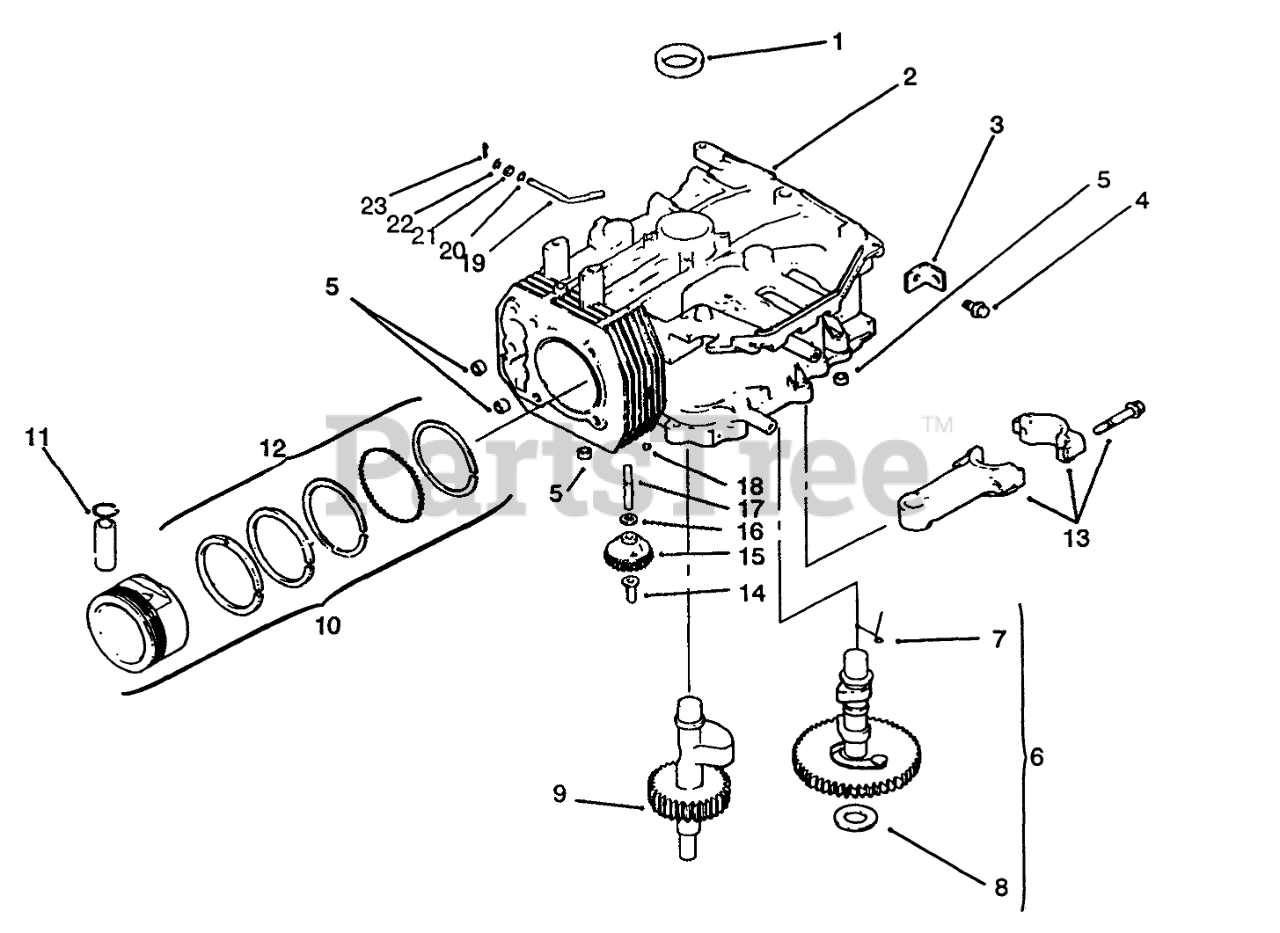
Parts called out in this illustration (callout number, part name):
1	Seal-Crankshaft (Only On: 72042, 72063, 72062, 72043)
3	Strap-lifting (Only On: 72042, 72063, 72062, 72043)
4	Screw M8x1.25x22 (Only On: 72042, 72063, 72062, 72043)
5	Dowel-Locating (Only On: 72042, 72063, 72062, 72043)
6	Kit-Camshaft INC 7-8 (Only On: 72042, 72063, 72062, 72043)
7	Spring-Actuating (Only On: 72042, 72063, 72062, 72043)
8	Shim-Camshaft A/R (Only On: 72042, 72063, 72062, 72043)
8	Shim-Camshaft A/R (Only On: 72042, 72063, 72062 72043)
9	Shaft-Balance (Only On: 72042, 72063, 72062, 72043)
10	Piston ASM STD INC 11-12 (Only On: 72042, 72063, 72062, 72043)
10	Piston ASM .25 INC 11-12 (Only On: 72042, 72063, 72062, 72043)
10	Piston ASM .50 INC 11-12 (Only On: 72042, 72063, 72062, 72043)
11	Retainer-Piston Pin (Only On: 72043, 72042, 72063, 72062)
12	Ring Set STD (Only On: 72042, 72063, 72062, 72043)
12	Ring Set .25 (Only On: 72043, 72042, 72063, 72062)
12	Ring Set .50 (Only On: 72042, 72063, 72062, 72043)
13	Connecting Rod STD (Only On: 72042, 72063, 72062, 72043)
13	Connecting Rod .25 (Only On: 72042, 72063, 72062, 72043)
14	Pin-Governor Regulating (Only On: 72042, 72063, 72062, 72043)
15	Gear-Governor ASM (Only On: 72042, 72063, 72062, 72043)
16	Washer-Governor (Only On 72042, 72063 72062, 72043)
17	Shaft-Governor Gear (Only On: 72042, 72063, 72062, 72043)
18	Plug-Cup (Only On: 72042, 72063, 72062, 72043)
19	Shaft-Governor Cross (Only On: 72042, 72063, 72062, 72043)
20	Washer-Governor Shaft (Only On: 72042, 72063, 72062, 72043)
21	Seal-Governor Shaft (Only On: 72042, 72063, 72062, 72043)
22	Washer-Flat (Only On: 72042, 72063, 72062, 72043)
23	Pin-Governor Hitch (Only On: 72042, 72063, 72062, 72043)
